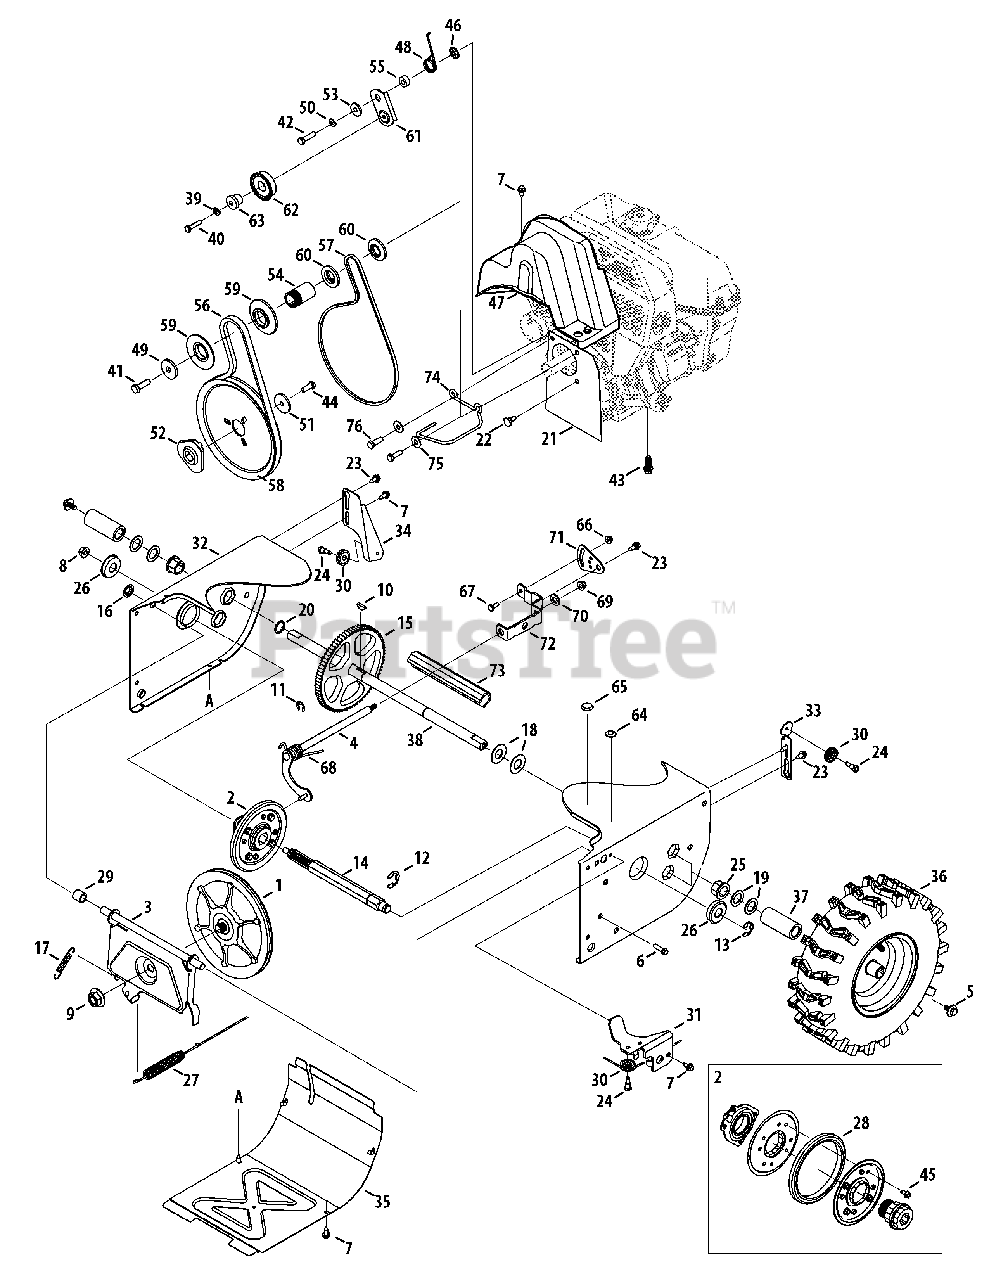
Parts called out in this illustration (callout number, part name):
1	Disc Assembly, Friction Wheel
2	Friction Wheel Assembly, 5.5 OD
3	Support Bracket, Friction Wheel
4	Shift Assembly, Rod
5	Screw, 5/16-24, .750, Gr5
6	Screw, 1/4-20, 1.000
7	Screw, 1/4-20 x .625
8	Nut, Flange Lock, 3/8-16, Nylon
9	Nut, Flange, 5/8-18
10	Key, Hi Pro, 3/16 x 3/4 Dia.
11	E-ring, .500 Dia.
12	E-ring, Retaining, .875 Dia.
13	E-ring, .750 Dia.
14	Hex Shaft, .8125, 7-Tooth
15	Gear, 80-Tooth
16	Speed Nut, .500
17	Extension Spring
18	Washer, Flat, .760 x 1.490 x .060
19	Washer, Flat, .793 x 1.24 x .060
20	Washer, Flat, .75 x 1.00 x .060
21	Plate, Cover
22	Shoulder Screw
23	Screw, Shoulder, .37 x .105, 1/4-20
24	Screw, 1/4-28, .375
25	Bearing, Hex Flange x .75 ID
26	Bearing, Ball, 17 x 40 x 12
27	Clutch Cable, Wheel, 44.95"
28	Rubber, Friction Wheel, 5.5 OD
29	Spacer, .508 ID x .75 OD x .68
30	Roller, Cable
31	Front Guide Bracket, Auger Cable
32	Frame
33	Guide Bracket, Auger Cable
34	Guide Bracket, Drive Cable
35	Cover, Frame
36	LH Wheel Assembly
36	RH Wheel Assembly
37	Spacer, 1.25 x .75 x 3.0
38	Axle, .75 x 22"
39	Washer, Lock, 1/4
40	Hex Screw, 1/4-20, 1.25, Gr5
41	Hex Screw, 3/8-24, 1.25, Gr8
42	Hex Screw, 5/16-24, 1.25, Gr5
43	Screw, Sems, 3/8-16, 1.00
44	Hex Screw, 5/16-24, .875, Gr8
45	Screw, 5/16-18 x .750
46	Nut, Push-on, .25 Dia.
47	Cover, Belt
48	Spring, Torsion, .850 ID x .354
49	Washer, Flat, .45 x 1.5 x .172
50	Washer, Lock .3125
51	Washer, Flat, .34 x 1.50 x .150
52	Pulley, Adapter, .75 Dia.
53	Spacer, Shoulder, .317 x .50 x .102
54	Spacer, .875 ID x 1.185 OD
55	Spacer, .340 x .750 x .360
56	Belt, Auger Drive
57	Belt, Wheel Drive
58	Pulley, Auger Drive, 8.1 x .5
59	Pulley, Half, V x 2.600 OD
60	Pulley, Half, 3/8-V x 1.7160 OD
61	Idler Bracket, Wheel Drive
62	Idler Pulley Assembly
63	Spacer, Shoulder, .26 x .79 x .538
64	Plug, 3/8 ID
65	Plug, 1/2 ID
66	Nut, Flange Lock, 1/4-20, Nylon
67	Hex Screw, 1/4-20, .620, Gr5
68	Spring, Torsion, .750 ID x .968
69	Nut, Flange Lock, 5/16-18, Nylon
70	Wash., Flat, .469 x .875 x .105
71	Pivot Bracket, Speed Selector
72	Shift Bracket, Speed Selector
73	Spacer, Axle
74	Belt Guide
75	Flat Washer, .349 x .879 x .063
76	Screw, 5/16-24 x 1.00
